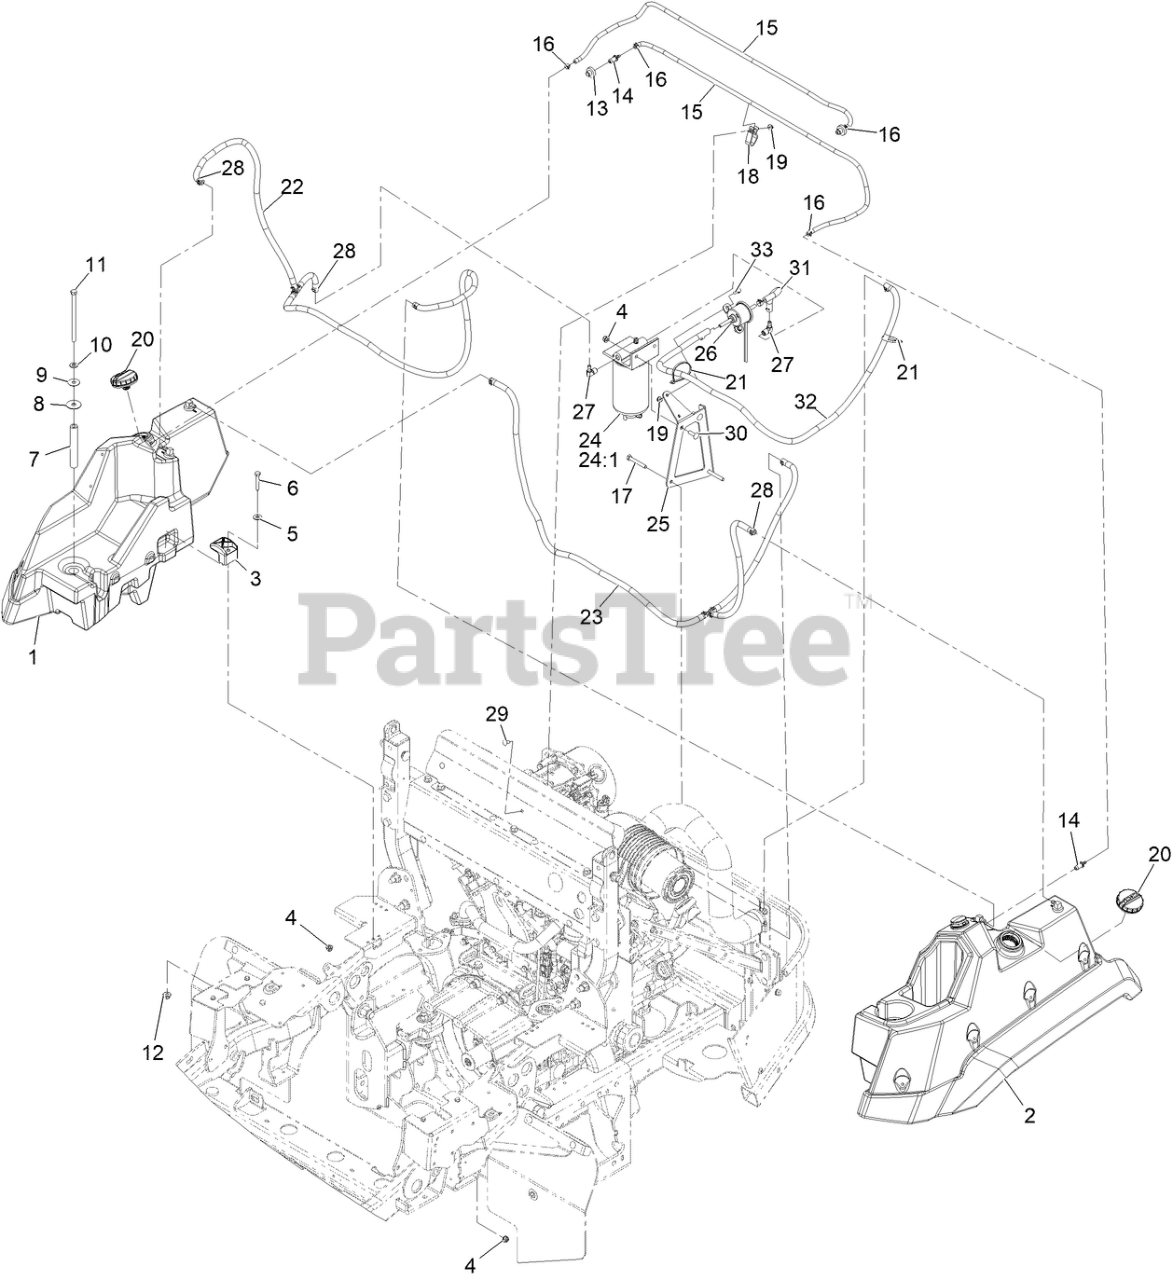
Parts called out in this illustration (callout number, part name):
1	RH FUEL TANK ASM
2	LH FUEL TANK ASM
4	NUT-HF, NI
5	WASHER-FLAT
6	SCREW-HH
7	TUBE-SPACER
8	WASHER-RUBBER
9	WASHER-PLAIN
10	WASHER-FLAT
11	SCREW-HH
12	NUT-HF, NI
13	BUSHING
14	FITTING-ORIFICE, STRAIGHT
15	HOSE-VENT, TANK
16	CLAMP-HOSE
17	SCREW-CARR
18	CLAMP-HOSE
20	CAP-FUEL, DIESEL
21	TIE-CABLE
22	FUEL SUCTION LINE ASM
23	FUEL RETURN LINE ASM
24	FILTER-WATER/FUEL SEPERATOR
24:1	FILTER-FUEL/WATER SEP.
25	BRACKET-FILTER, FUEL
26	PUMP-FUEL, ELECTRIC
27	FITTING-HYD, 90
28	CLAMP-HOSE
29	SCREW-HH
30	SCREW-CARR
31	HOSE-FUEL
32	HOSE-FUEL
33	SCREW-HWH
